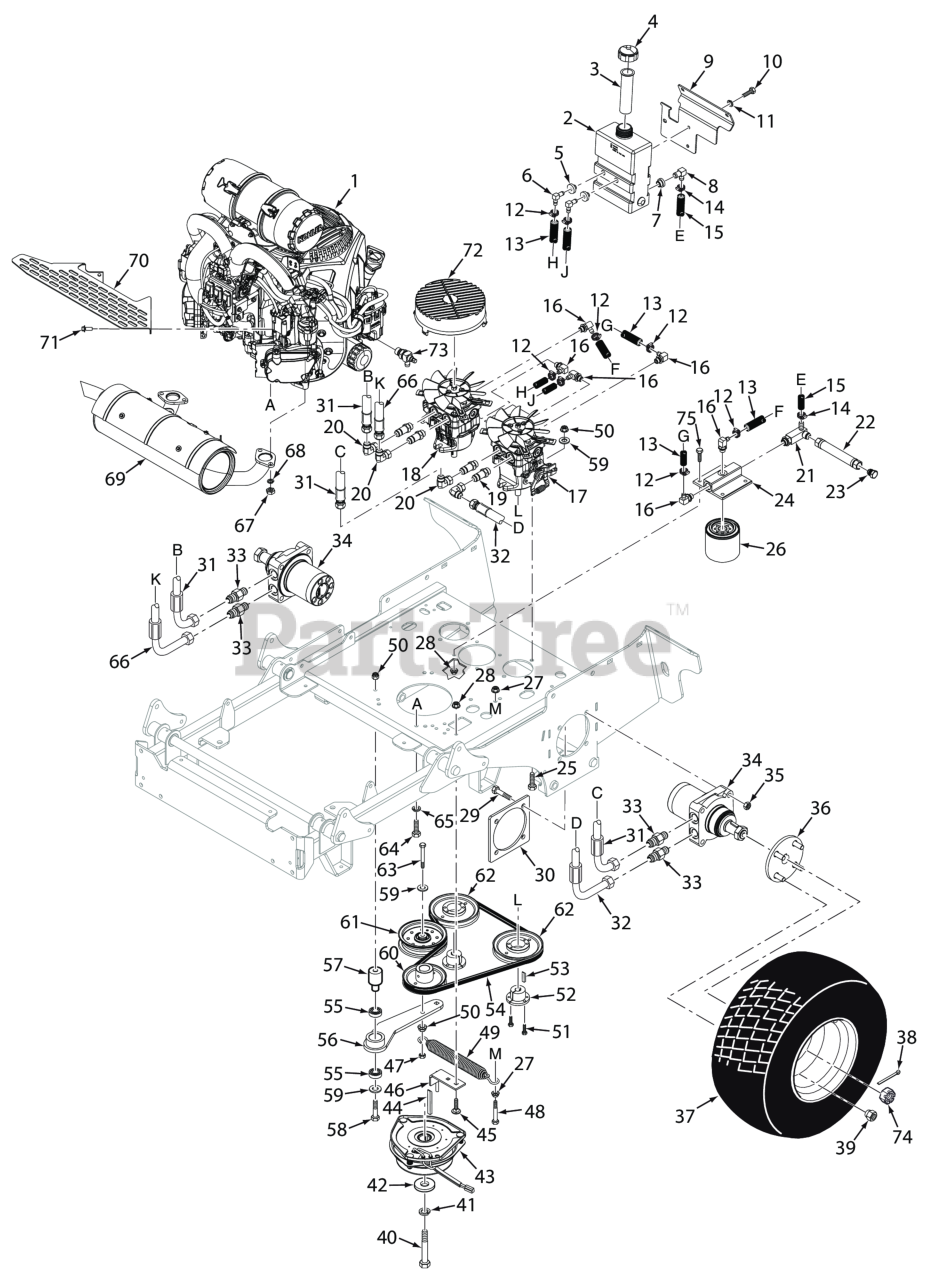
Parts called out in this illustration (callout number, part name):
1	Engine, 22 HP Kawasaki FX
1	Engine, 23hp Kawasaki FX730V
1	Engine, 25 HP Kohler EFI
1	Engine, 25hp Kawasaki FX801V
1	Engine, 29 HP Kohler EFI
1	Engine, 31 HP Kohler EFI
2	Hydro Tank Assy., SVRII
3	Insert, Filler Neck
4	CAP, HYDRAULIC TANK
5	Bushing, 0.56" Dia. Viton
6	Elbow, 90 Degree, 9/16-18 JIC x 9/16 O-Ring
7	Bushing, 0.78" Dia. Viton
8	Fitting, 90 Degree - 1/2" Hose
9	Bracket, Hydro Tank Mounting
10	BOLT, SERRATED FLANGE HEX HEAD 5/16-18 X 3/4"
11	Lockwasher, 5/16 (.317 x .586 x .078) Helical Spring
12	Clamp, .69" Max. / .25" Min. Dia.
13	Hose, 3/8" ID - 10-1/4" Long (Order By The Inch)
14	Clamp, Cable 3/4" I.D.
15	Hose Assembly, 1/2" ID (Oil Reservoir to Filter Base)
16	Elbow, 90 Degree - 9/16" O-Ring x 3/8" Hose
17	Pump, LH - SVRII
18	Pump, RH - SVRII
19	Union, O-Ring to JIC
20	Elbow, 1/2 JIC Female to 1/2 JIC Male
21	Tee, 3/4" O-Ring
22	Drain, Hose Assembly
23	Plug, JIC 3/4-16 UNF
24	Filter Head Assembly
25	Bolt, Hex Head, 3/8-16 x 1-1/2"
26	OIL FILTER, SPECIAL
27	NUT, 3/8-16 SERRATED FLANGE HEX HEAD
28	Nut, Serrated Flange 5/16-18 (Right Front Engine Mounting, Briggs and Kohler Only)
29	Bolt, Hex Hd. 1/2-13 x 2-1/2" (lower)
30	Plate Weldment, Motor Backing
31	Hose Assy., 27-1/2"
32	Hose Assy., 15-1/4"
33	TUBE UNION, 3/4-16 JIC TO 7/8-14 "O" RING
34	Wheel Motor, SVRII
34	Key, Woodruff 5/16 x 1"
35	Locknut, Hex 1/2-13 Center Lock
36	Wheel Hub Assy., SVRII
36	Bolt, Serr. Flange 1/2-20 x 4.563"
37	Wheel Assy., 24 x 9.5 - 12 (4-Ply) (48 / 52)
37	Tire 24 x 9.5-12 (48" & 52" Deck)
37	Rim w/Stem
38	Pin, Cotter 9/16" x 1-1/2"
39	Wheel Nut, 1/2-20 x 13/16
40	Bolt, Hex Head 7/16-20 x 2-1/4" w/Patch (Kawasaki)
41	Lockwasher, 7/16� Spring
42	Flatwasher, 7/16-.469 x 1.75 x .25 (48, 52)
43	Clutch w/Tag GT2.5-FE02 (48 / 52)
44	Key, 1/4 x 1/4 x 3-1/2"
45	Bolt, 5/16-18 x .75 RHSN Carriage
46	ANTI-ROTATION WLMT, SVRII
47	Bolt, Hex Head 3/8-16 x 1" Ser. Flg.
48	Bolt, Hex Head 3/8-16 x 3" - 52"
49	Spring, Transmission Idler
50	HEX NUT, ELASTIC STOP LOCK, 3/8-16
51	Bolt, Hex Head 1/4-20 x 1" Grade 8 Black
52	Hub, Tapered, 15mm Bore
53	KEY, 5 MM X 5 MM X 25 MM
54	Belt, Pump Drive (48 & 52)
55	BEARINGS, BALL, NEUTRAL RETURN
56	Idler Arm Assy.
57	Pivot, Idler
58	Capscrew, Hex Head 3/8-16 x 3.25"
59	Flatwasher, 3/8 (.391 x .938 x .105 HD) Grade 8
60	Pulley, 4-3/4" OD - 1.125 Bore
61	Pulley, Idler 4-1/2"
62	Pulley, 5.45 OD - Tapered Bore"
63	Bolt, Hex Head 3/8-16 x 2-3/4" Full Thread
64	Bolt, Hex Head 3/8-16 x 1-1/4", Kawasaki FX / FS
64	Bolt, Hex Head Self-Tap 3/8-16 x 1-1/4" (Kohler x3 - 25EFI, Kohler x4 - 29EFI)
64	Bolt, Hex Head 5/16-18 x 1-1/2" (Right Front Engine Mounting, Briggs and Kohler Only)
64	Lockwasher, 5/16" Ext. Tooth (Kohler x1)
64	Nut, Serrated Flange 5/16-18 (Right Front Engine Mounting, Briggs and Kohler Only)
65	Lockwasher, 3/8" Spring, Kawasaki FX / FS
66	Hose Assy., 30"
67	Nut, M8 x 1.25 Hex Special
67	Lock Nut, M8-1.25 -8H (Kohler)
68	Lockwasher, M8 Spring (Kawasaki)
69	Muffler, Kawasaki FX - SVRII
69	Muffler, Kohler CV-EFI - SVRII
69	Muffler, Kawasaki FX801 - SVRII
69	Muffler, Kohler, 29 EFI - SVRII
70	Heatshield, Muffler - Kawasaki FX - SVRII
70	Heatshield, Muffler - Kawasaki FX801 - SVRII
70	Heatshield, Muffler - Kohler 29 EFI - SVRII
71	Bolt, Hex Head M8 - 1.25 x 20
71	BOLT, SERRATED FLANGE HEX HEAD 5/16-18 X 3/4"
71	Flatwasher, 5/16-.344 x .688 x .065 (48V / 52V)
71	Nut, Serrated Flange 5/16-18 (Right Front Engine Mounting, Briggs and Kohler Only)
72	Fan Cover, Pump
73	Oil Drain, M20 Thread (Kawasaki)
73	Extension, Oil Drain 2.3" - Kawasaki
73	Tubing, Oil Drain (order by inch)
74	Nut, Hex Castle 1.0-20 UNEF
75	Bolt, Heax Head 5/16-18 x 1" (48V / 52V)
